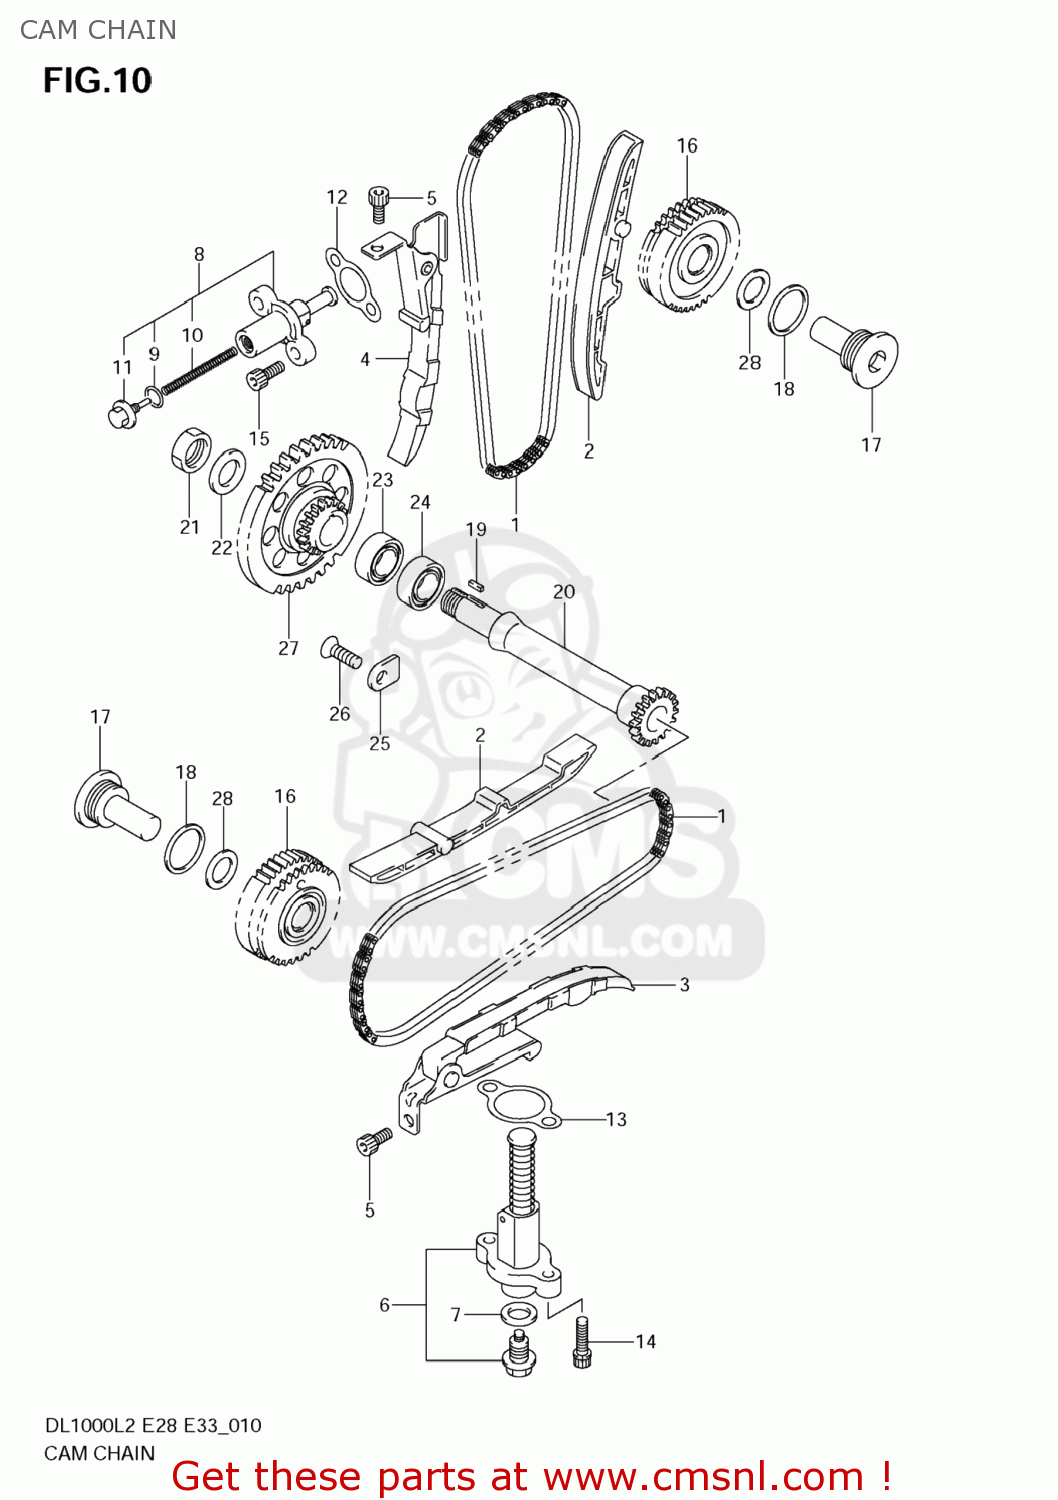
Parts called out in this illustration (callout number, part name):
1	CHAIN,CAMSHAFT DRIVE
2	GUIDE,CAM CHAIN
3	TENSIONER,CAM CHAIN FR
4	TENSIONER,CAM CHAIN RR
5	BOLT
6	ADJUSTER ASSY,TENSIONER FR
7	GASKET(12X21X2) (NAS)
8	ADJUSTER ASSY,TENSIONER
9	O RING
10	SPRING
11	PLUG,ADJUSTER
12	GASKET,TENSIONER ADJUSTER (NAS)
13	GASKET,TENSIONER ADJUSTER (NAS)
14	BOLT
15	BOLT
16	GEAR,CAM CHAIN IDLER NO.2
17	SHAFT,IDLER NO.2
18	GASKET(26.5X30.5X1) (NAS)
19	KEY
20	SHAFT,IDLER
21	NUT
22	SHIM(16X26X1.5)
23	BEARING
24	BEARING(25X47X8)
25	RETAINER,COUNTER BEARING,R
26	SCREW(6X12)
27	SPROCKET,IDLER NO.1
28	SHIM(15X24X1)
